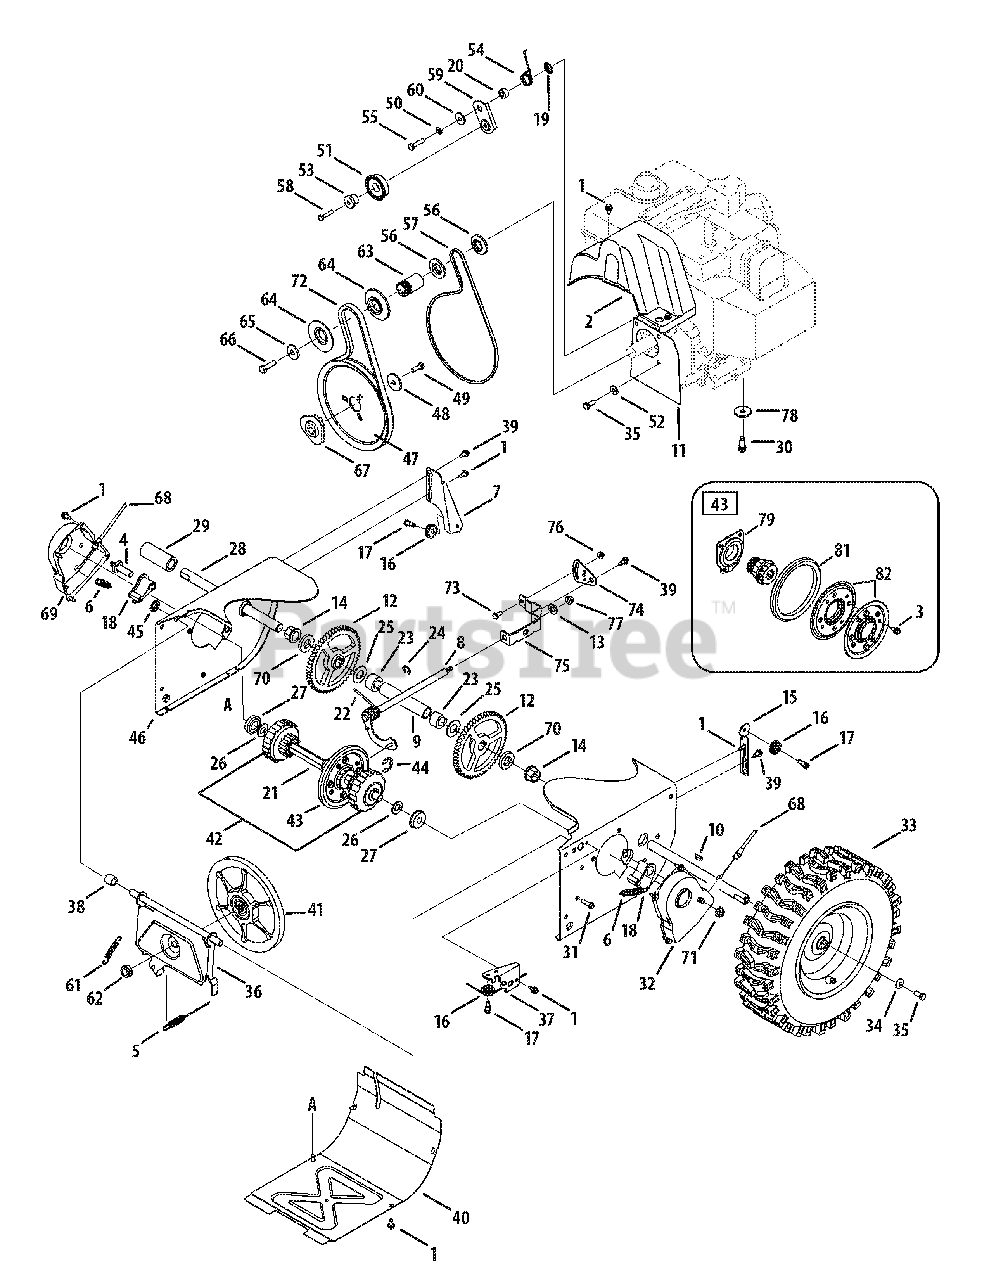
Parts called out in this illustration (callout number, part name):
1	AB Screw, 1/4-20 x 0.625
2	Belt Cover
3	AB Screw
4	Actuator Shaft
5	Drive Clutch Cable
6	Extension Spring
7	Drive Clutch Cable Guide Bracket
8	Shift Rod Assembly
9	Axle Support Tube
10	Hi-pro Key
11	Cover Plate
12	Gear, 56T
13	Flat Washer
14	Hex Flange Bearing
15	Auger Clutch Cable Guide Bracket
16	Cable Roller
17	C Screw, 1/4-28 x 0.375
18	Dogg Assembly - LH
18	Dogg Assembly - RH
19	Speed Nut
20	Spacer
21	Hex Drive
22	Torsion Spring, .750ID x .968 Lg.
23	Spacer
24	E Ring
25	Flat Washer, .76 x 1.49 x .06
26	Flat Washer
27	Ball Bearing
28	Axle
29	Spacer
30	TT Sems Screw, 3/8-16 x 1.0
31	TT Screw, 1/4-20 x 1.0
32	Shaft Retainer - LH
33	X-Trac RH, 16 x 6.5 x 8
33	X-Trac LH, 16 x 6.5 x 8
34	Bell Washer
35	Hex Bolt, 5/16-24 x 0.75
36	Friction Wheel Support Brkt. Assy.
37	Auger Cable Guide Bracket
38	Spacer
39	Shoulder Screw
40	Frame Cover
41	Friction Wheel Disc Assembly
42	Drive Shaft Assembly
43	Friction Wheel Assembly
44	Retainer Ring
45	Speed Nut
46	Wheel Drive Frame
47	Auger Pulley
48	Flat Washer
49	Hex Bolt, 5/16-24 x 0.875
50	Lock Washer
51	Pulley Assembly
52	Shoulder Spacer
53	Spacer
54	Torsion Spring
55	Hex Screw, 5/16-24 x 1.25
56	Pulley Half
57	V-Belt, 2L x 33
58	TT Screw, 1/4-20 x 1.25
59	Drive Clutch Idler Bracket
60	Shoulder Spacer
61	Extension Spring
62	Jam Lock Nut, 5/8-18
63	Spacer
64	Pulley Half
65	Flat Washer
66	Hex Bolt, 3/8-24 x 1.25
67	Pulley Adapter
68	Steering Cable
69	Shaft Retainer - RH
70	Axle Spacer
71	Flange Lock Nut, 3/8-16
72	V-Belt,.500 x 35.00 Lg
73	Hex Screw, 1/4-20 x .620
74	Speed Selector Pivot Bracket
75	Speed Selector Shift Bracket
76	Flange Lock Nut 1/4-20
77	Flange Lock Nut 1/4-20
78	Flat Washer
79	Bearing Assembly
81	Friction Wheel Rubber
82	Friction Wheel Plate
